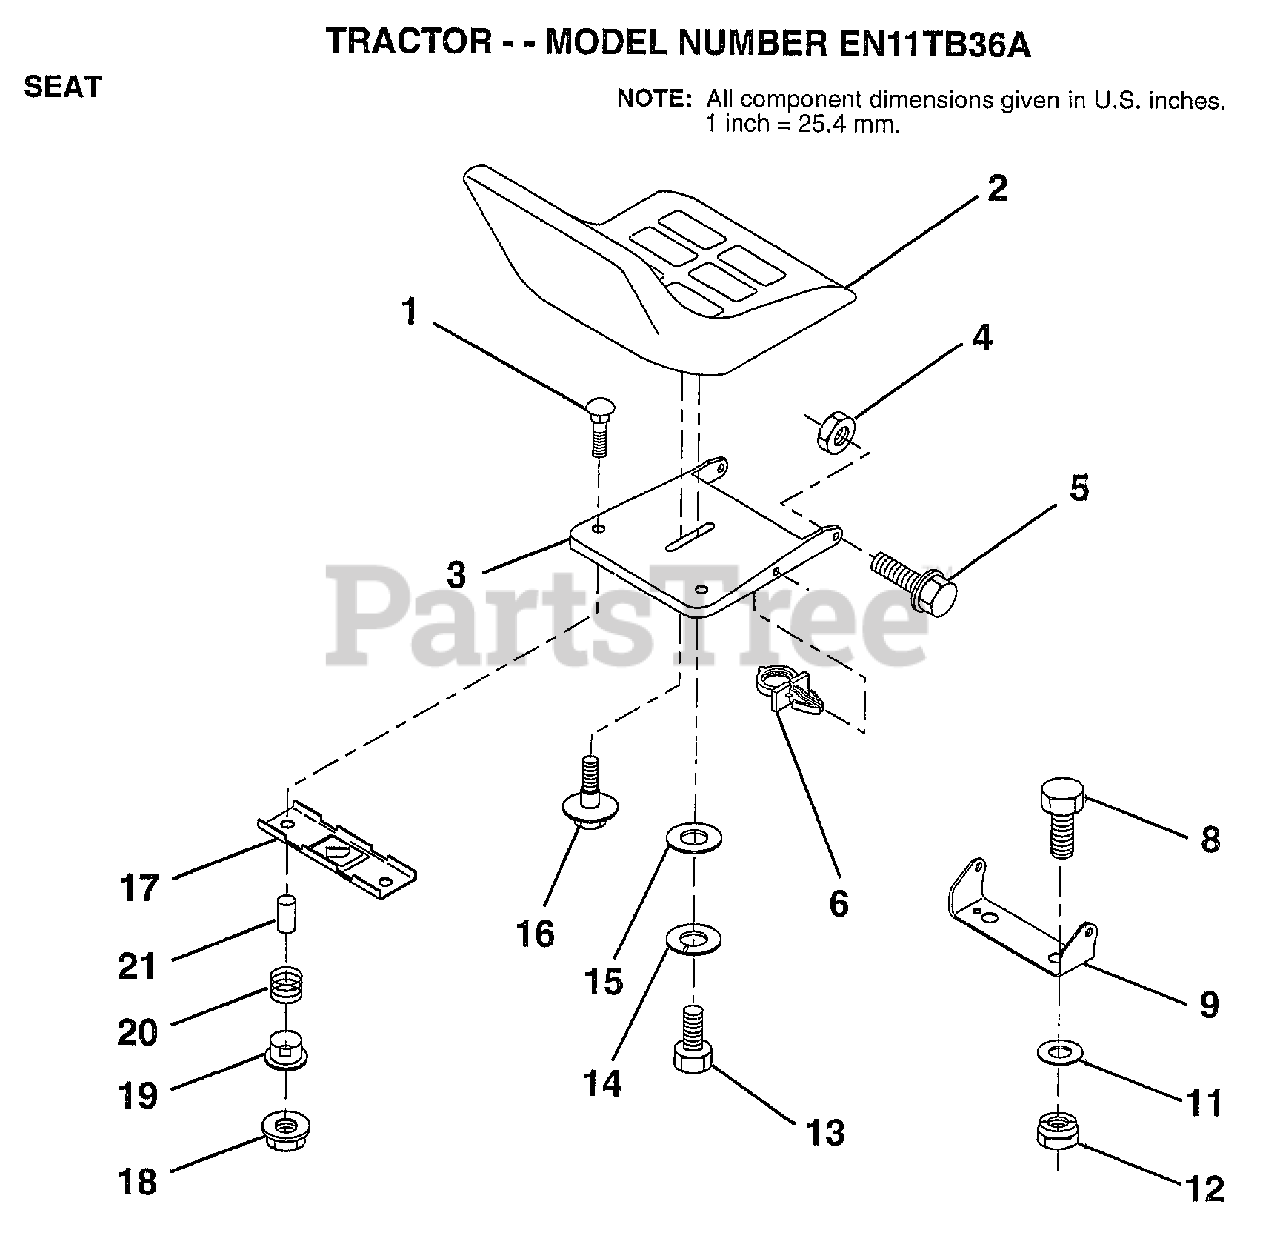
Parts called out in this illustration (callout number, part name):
1	BOLT-RD HD SQ NK
3	PAN-SEAT
4	NUT
5	"BOLT,SHOULDER"
6	CLIP.PUSH-IN.HING
8	BOLT
9	BRACKET PVT SEAT
11	WASHER
12	NUT
13	BOLT
14	LOCKWASHER
15	WASHER
16	"BOLT,SHOULDER"
17	BRKT SWITCH
19	BUSHING
20	SPRING
21	SPLIT SPACER
